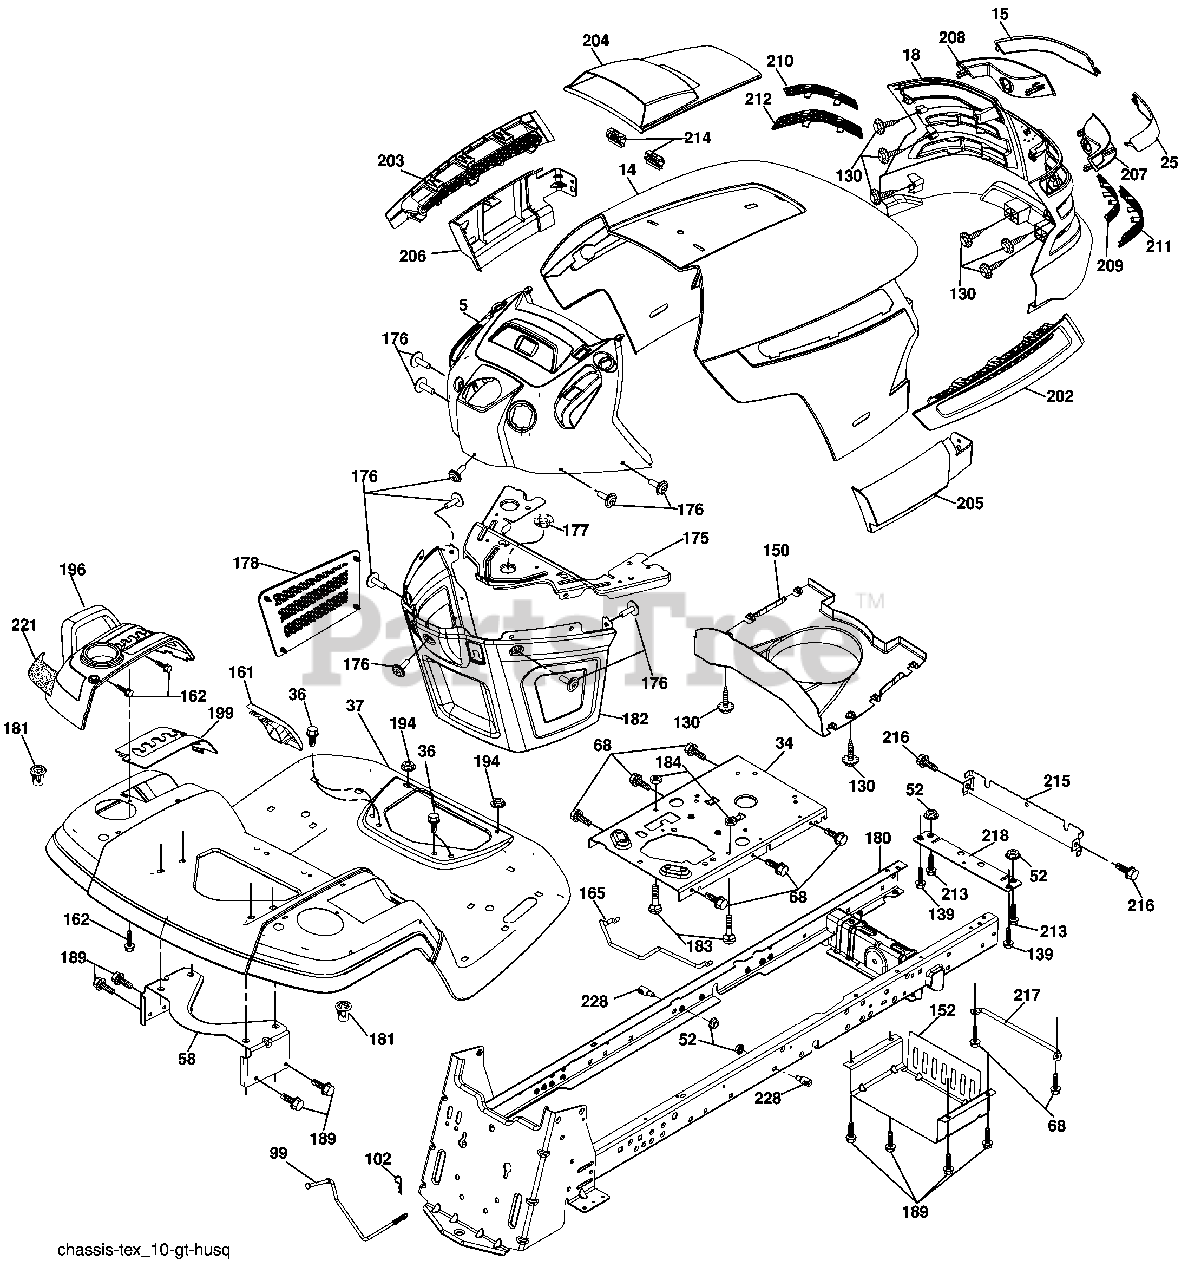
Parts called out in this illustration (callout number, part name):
5	Dash
14	Hood
18	Grille
34	Plate Engine
36	Screw 5/16-18 x 3/4
37	Fender
58	Bracket Fender
68	Screw 5/16-18 x 1/2
99	Rod Bypass Asm.
102	Retainer Spring 1''
130	Screw 10 x 3/4 Single Lead Hex
139	Bolt Shoulder 5/16-18
150	Duct Heat Hood
152	Shield Browning/Debris
161	Console Fuel Window
162	Screw Hex Wsh Hi-Lo 1/4 x 1/2
165	Bracket Support Tank
175	Crossmember
176	Screw 10-24 x 5/8 RND Qdrx
177	Bushing Steering
178	Cargo Asm. Net
180	Chassis
181	Bushing Mtg. Fender Crgo.
182	Dash Lower
183	Bolt 5/16-18 x 1-1/4
184	Spacer Fender
189	Screw 5/16-18 x 3/4
194	Nut Lock Hex Flange 5/16-18
196	Console Asm. Deck Lift
199	Plate Deck Lift
202	Vent Side Hood RH
203	Vent Side Hood LH
204	Vent Asm Hood Top
205	Skirt Hood Side RH
206	Skirt Hood Side LH
209	Insert Hex Top RH
210	Insert Hex Top LH
211	Insert Hex Bottom RH
212	Insert Hex Bottom LH
213	Bolt Hex Hd 5/16-18 unc x 3/4
214	Clip Retainer
215	Cover Chassis Front
216	Screw 5/16-18 x 1/2
217	Rod Pivot
221	Refl ector LH
228	Stud Fastener
